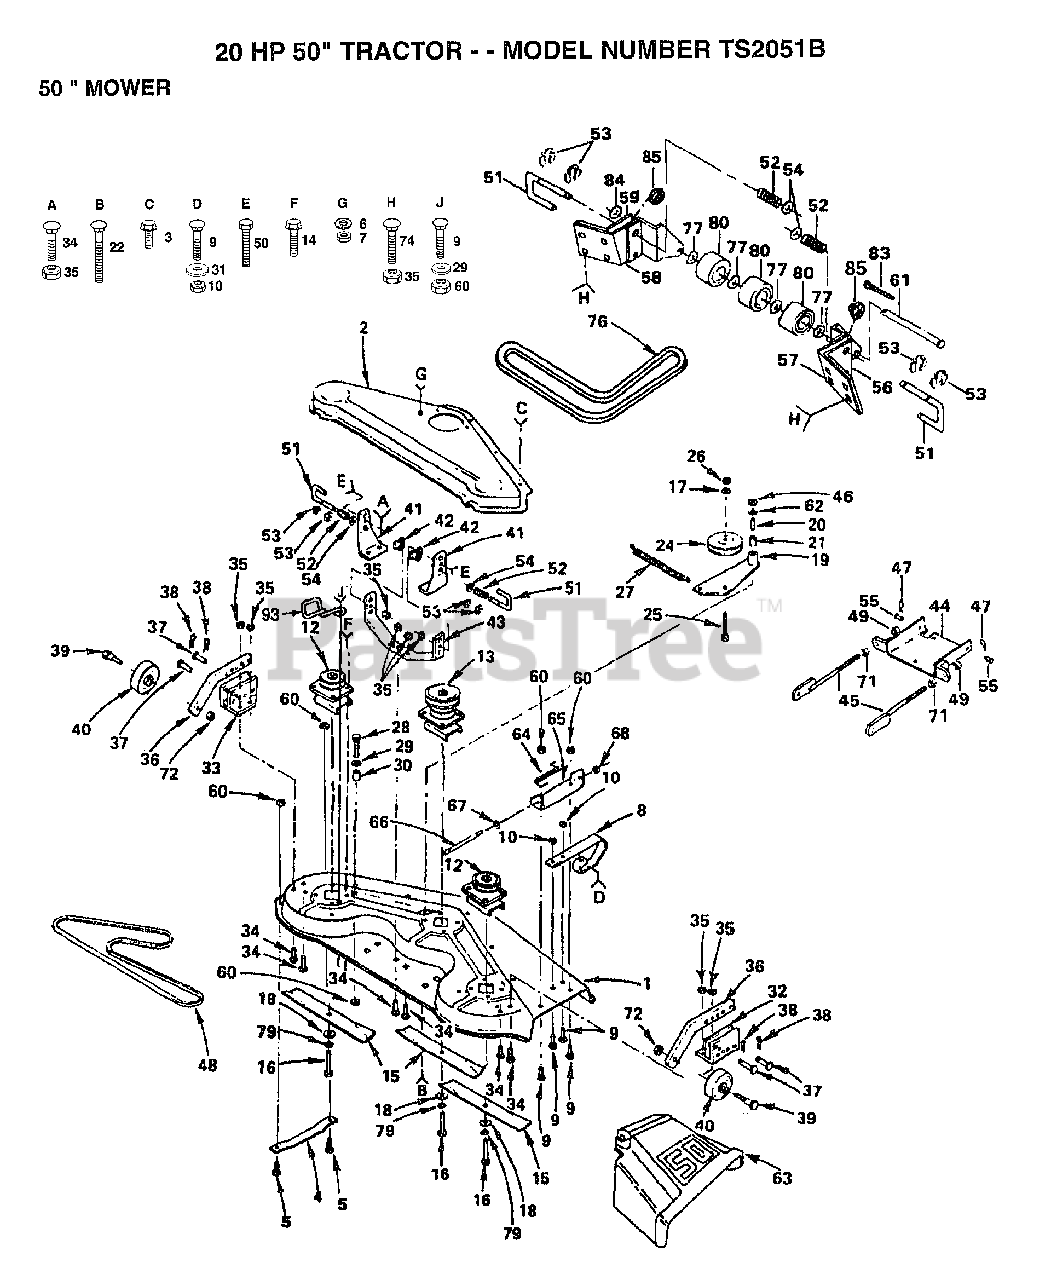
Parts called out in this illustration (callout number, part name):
2	CVR DRIVE DECK
3	SCREW LT
4	RUNNER-LH M
5	BOLT
6	LOCKWASHER
7	NUT.HEX.5/16-18
9	BOLT
14	SCREW
15	"BLADE.50""STD.LIFT"
16	BOLT.3/8-24X1-1/2
17	LOCKWASHER
18	WASHER
19	ARM ASSY GT
22	BOLT
24	IDLER-FLAT T
26	NUT.HEX.3/8-16UNC
27	SPRING T
28	BOLT
29	WASHER M
30	SPACER SPLIT LT
31	WASHER
32	GUAGE WHL BRKT GT
33	GUAGE WHL BRKT GT
34	BOLT
36	GUAGE WHL BAR GT
37	PIN.CLEVIS
39	BOLT.SHOULDER
40	WHEEL GAGE DONUT
41	SUSP BRKT GT
42	SPACER GT
43	SUSP BRACE GT
45	BRACKET.SUSPEN.AS
46	JAM NUT TI
47	RETAINER.SPRING
48	V-BELT M
49	NUT LTV
50	BOLT
51	RELEASE PIN GT
52	SPRING M
53	KLIP RING
55	CLEVIS PIN GT
56	BRACKET T
57	BRACKET T
58	BRACKET T
59	BRACKET T
61	PIVOT PIN T
63	DEFLECTOR
64	SPRING TORSION
65	BRKT DEFLECTOR
66	ROD-HINGE T
67	WASHER
68	NUT PUSH M
71	NUT
72	LOCKNUT
74	BOLT
76	BELT-V.93.5.MWR
77	WASHER T
80	ROLLER T
83	COTTER PIN
85	SPACER T
93	BELT RETIANER
